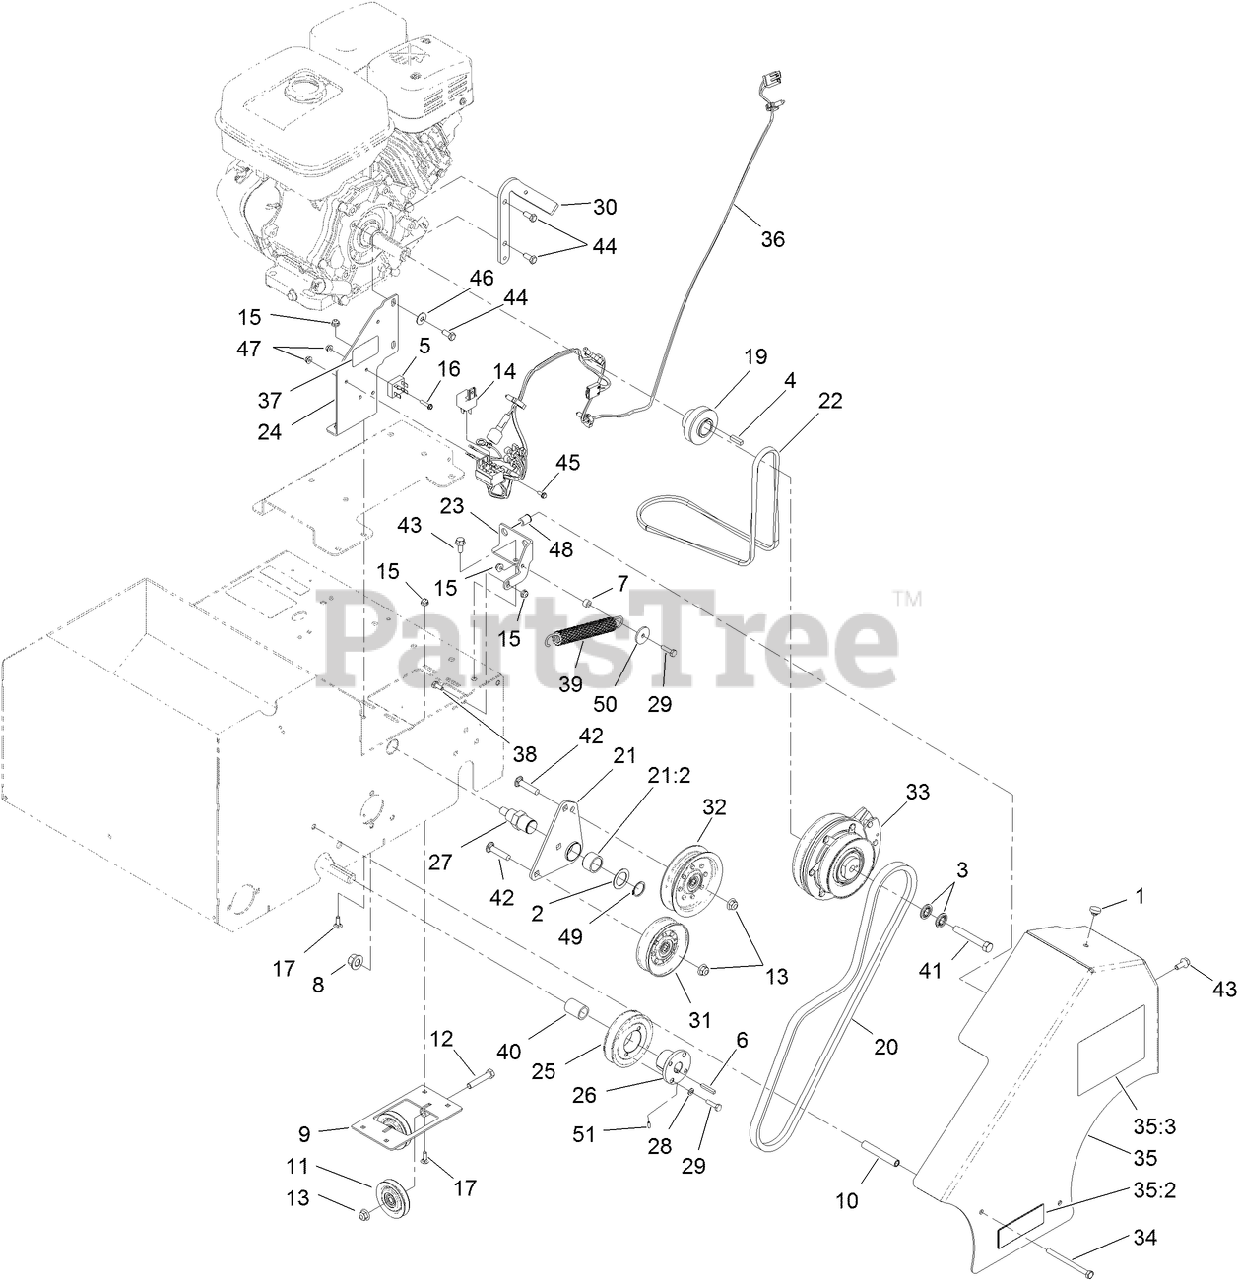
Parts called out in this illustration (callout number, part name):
1	BUMPER
2	WASHER-SPACER
3	WASHER-SPRING
5	RECTIFIER-BRIDGE
6	KEY-SQUARE
7	SPACER
8	NUT-LOCK
9	PULLEY-TENSION
10	SPACER-KICKSTAND, LONG
11	PULLEY-IDLER
12	SCREW-HH
13	NUT-HF, NI
15	NUT-HF
16	SCREW-HWH
17	BOLT-CARR
19	PULLEY-MULE DRIVE
20	BELT-SEEDER, CLUTCH
21	IDLER ARM ASM
21:2	BUSHING
22	BELT-MULE DRIVE
23	BRACKET-SPRING
24	SUPPORT-ENGINE
25	SHEAVE-TAPER LOCK
26	BUSHING-TAPER LOCK
27	PIVOT-IDLER
28	WASHER-LOCK
29	SCREW-HH
30	STOP-CLUTCH
31	PULLEY-IDLER V
32	PULLEY-IDLER FLAT (4.06-INCH)
33	CLUTCH-ELECTRIC
34	SCREW-HH
35	BELT GUARD ASM
35:2	DECAL-DANGER
35:3	DECAL-SEED GRAPH
36	HARNESS-SLICER/SEEDER
37	DECAL-BRIDGE RECTIFIER
38	SCREW-HH
39	SPRING-EXTENSION
40	SPACER
41	SCREW-HH
42	SCREW-CARR
43	SCREW-HHF
44	SCREW-HH
45	SCREW-HWH
46	WASHER-BELLEVILLE
47	NUT-LOCK, FLANGE
48	NUT-INSERT
49	RING-RETAINING
50	WASHER
51	SCREW-SET, HS
